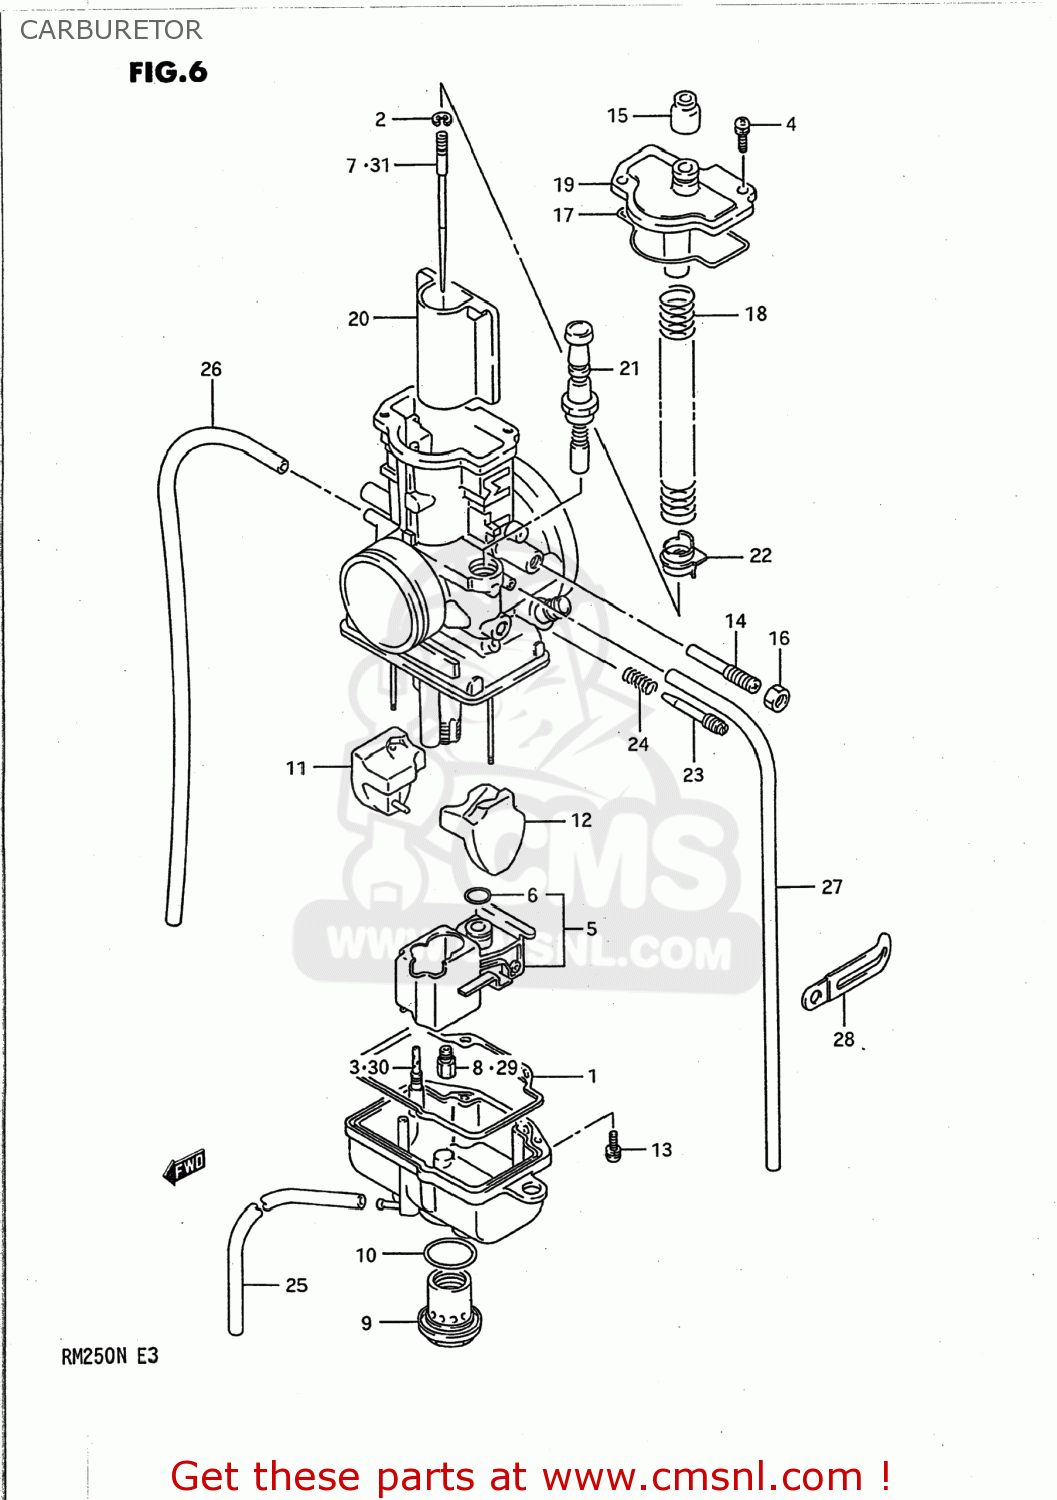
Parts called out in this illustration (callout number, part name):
1	O RING,FLOAT CHAMBER
2	CLIP,NEEDLE
3	JET,PILOT(55)
4	SCREW
5	VALVE ASSY,NEEDLE
6	O-RING,NEEDLE VALVE
7	NEEDLE JET
8	JET,MAIN(370)
9	CAP,DRAIN
10	O RING
11	FLOAT,R
12	FLOAT,L
13	SCREW
14	ADJUSTER
15	CAP
16	NUT
17	O RING,TOP CAP
18	SPRING
19	CAP,TOP
20	VALVE,PISTON(CA:3.5)
21	PLUNGER ASSY
22	RING
23	SCREW,AIR
24	SPRING
25	HOSE(3X5X600)
26	HOSE(3.5X6.5X600)
27	HOSE(3.5X6.5X600)
28	CLAMP
29	JET,MAIN(330)
30	JET
31	NEEDLE JET
